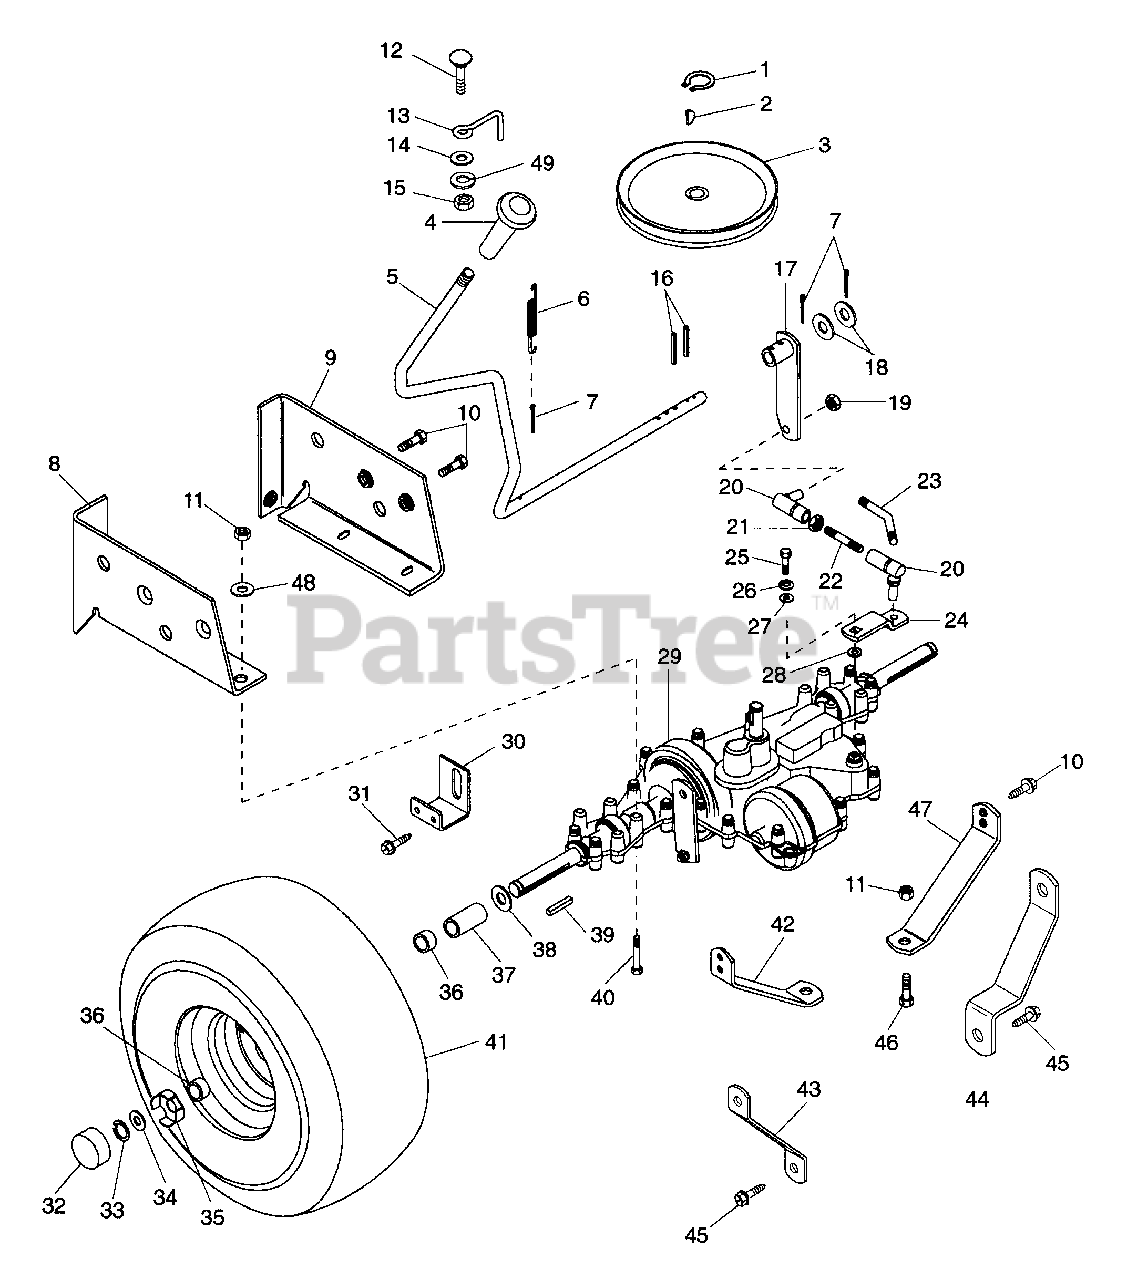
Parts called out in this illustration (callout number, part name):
1	RG-RTNG-EXT .625X.035
2	KEY-WDRF .188X.75X.313 SAE 9
3	PLY-TRANS 7.00X.626
5	LEVER - SHIFT
6	SG-TENS .063X.44X1.56
7	PIN-COTR .12X1.0 PL
8	MOUNT- TRANS. RH
9	MOUNT- TRANS. LH
10	SCR-TAP .375-16X.75 HWH PL TR
11	NUT-LK-TOP .312-18 GR C PL
12	BLT-RDHDSQNK.31-18X.75GR5SHTPL
13	FINGER - BELT
14	WSHR-FL-STL.344X.688X.065PL
15	NUT-HEX .312-18
16	PIN-GRV .188X1.25 TP A
17	ARM & HUB
18	WSHR-FL-STL .520X.827X.062 YZ
19	NUT-LK-CTR .312-24 PL
20	BALL JOINT- SNAP IN
21	NUT-JAM .312-24 PL
22	SHIFT LINK
23	LINK - SHIFT
24	SHIFT ARM
24	ARM - SHIFT 6 SPD
25	BLT-HEX .25-28X.75 PL GR8
26	WSHR-LK .250X.077 HVY PL
27	WSHR-FL-STL .328X1.0X.094 PL
28	WSHR-FL-STL .505X1.000X.062
29	TRANSAXLE-GEAR 5-SPD 940-011A
29	TRANSAXLE-GEAR 6-SPD 930-051A
30	SHIFT GUIDE BRACKET
31	SCR-TAP .312-18X.50 HWH PL TR
32	HUB CAP
33	RG-RTNG-EXT .750X.050
34	WSHR-FL-STL .755X1.375X.062 PL
35	SPINDLE CUP
36	SPACER .760X1.000X.575
37	BSHG-SLV .750X1.125X1.062
38	WSHR-FL-STL .755X1.375X.062 PL
39	KEY-SQ .188X2.0X.188 SAE 8630
40	BLT-HEX .31-18X2.50 PL GR5
41	T/WHL ASSY 20X8.00-8
41	RIM
41	TIRE 20X10-8 2P TS TL
41	T/WHL ASSY 18X6.50-8
41	TIRE
42	TORQUE STRAP- R
43	TORQUE STRAP
44	STRAP - TORQUE,LH 6 SPD
45	SCR-TAP .312-18X.75 HWH PL TR
46	BLT-HEX .31-18X2.00 PL GR5
47	TORQUE STRAP- L
48	WSHR-FL-STL .328X.875X.062 PL
49	WSHR-LK .312X.097 PL HVY
